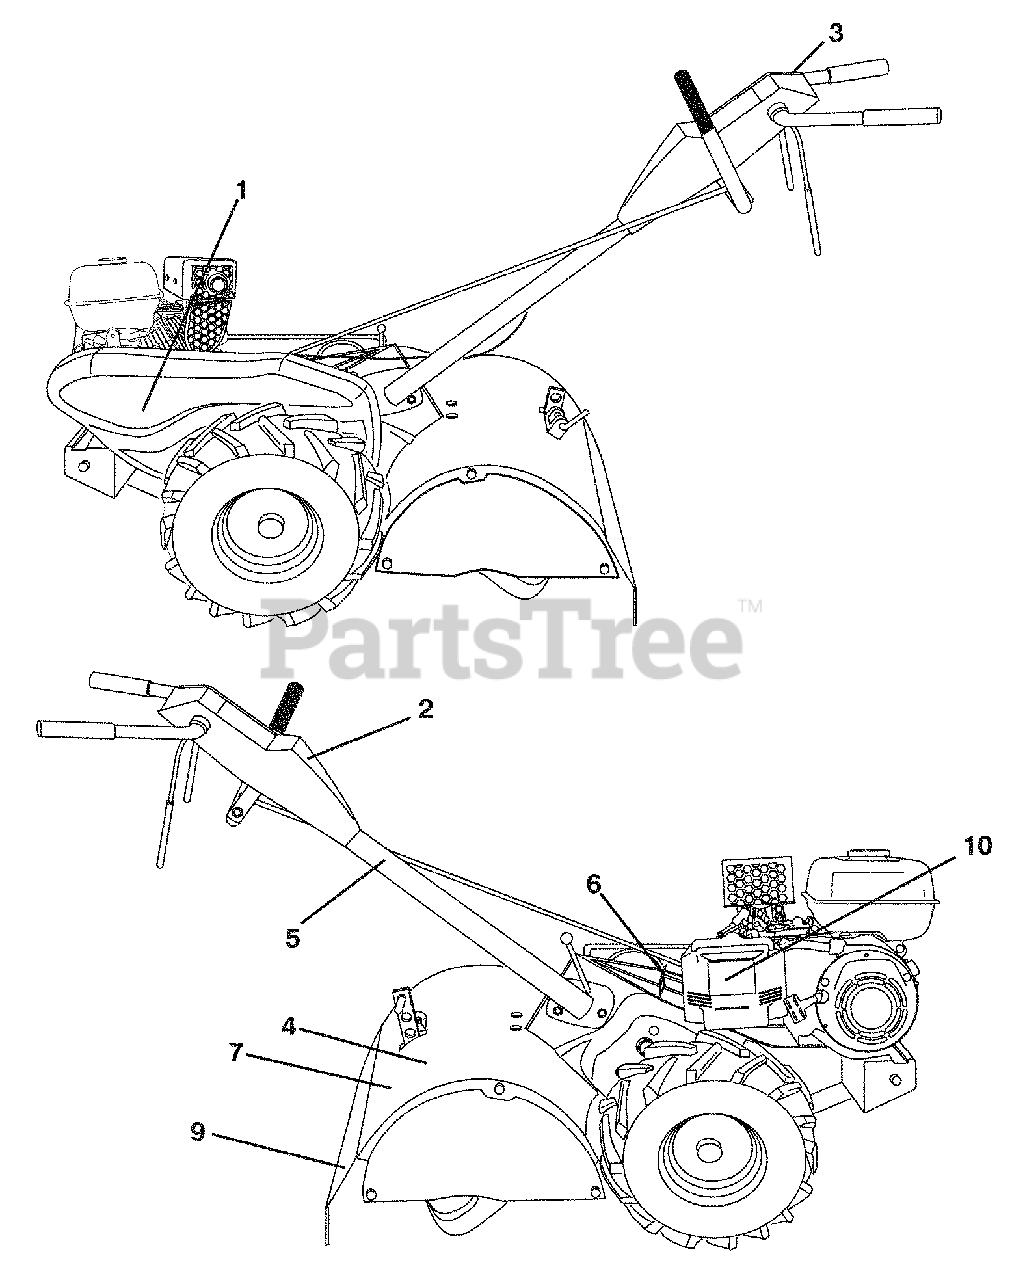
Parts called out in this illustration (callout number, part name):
1	Decal, Belt Guard
2	Decal, Console
3	Decal, Console Instruction
4	Decal, Tine Shield
5	Decal, Hand Placement
6	Decal, Shift Indicator
7	Decal, Warning
9	Decal, Warning, Rotating Tines
10	Decal, Engine, AC
